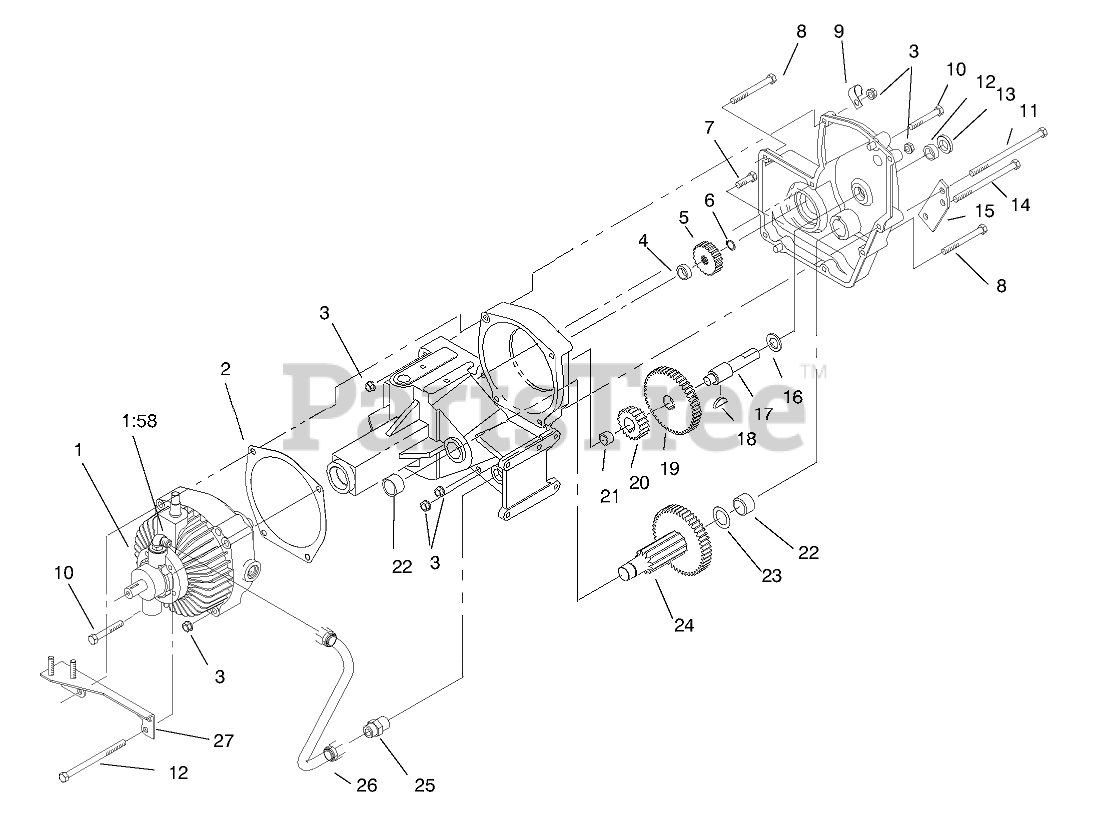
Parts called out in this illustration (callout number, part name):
1	TRANSMISSION-PUMP
2	GASKET
3	NUT-LOCK, NI
4	SPACER GEAR
5	GEAR 20 TEETH DRIVE
6	RING-SNAP, EXTERNAL
8	SCREW-HH
9	CLIP
11	SCREW-HH
12	NEEDLE BEARING
13	Seal
14	SCREW-HH
15	Bracket-Brake
16	Race Thrust
16:1	Case-Transaxle
16:2	DECAL - DANGER
17	SHAFT GEAR
18	Key
19	GEAR 46 TEETH
20	GEAR 20 TEETH
21	BEARING-NEEDLE
22	BEARING-NEEDLE
23	WASHER-THRUST
24	ASSY GEAR
25	FITTING-TUBE
26	ASSY-TUBE SUCTION
27	Plate-Control
